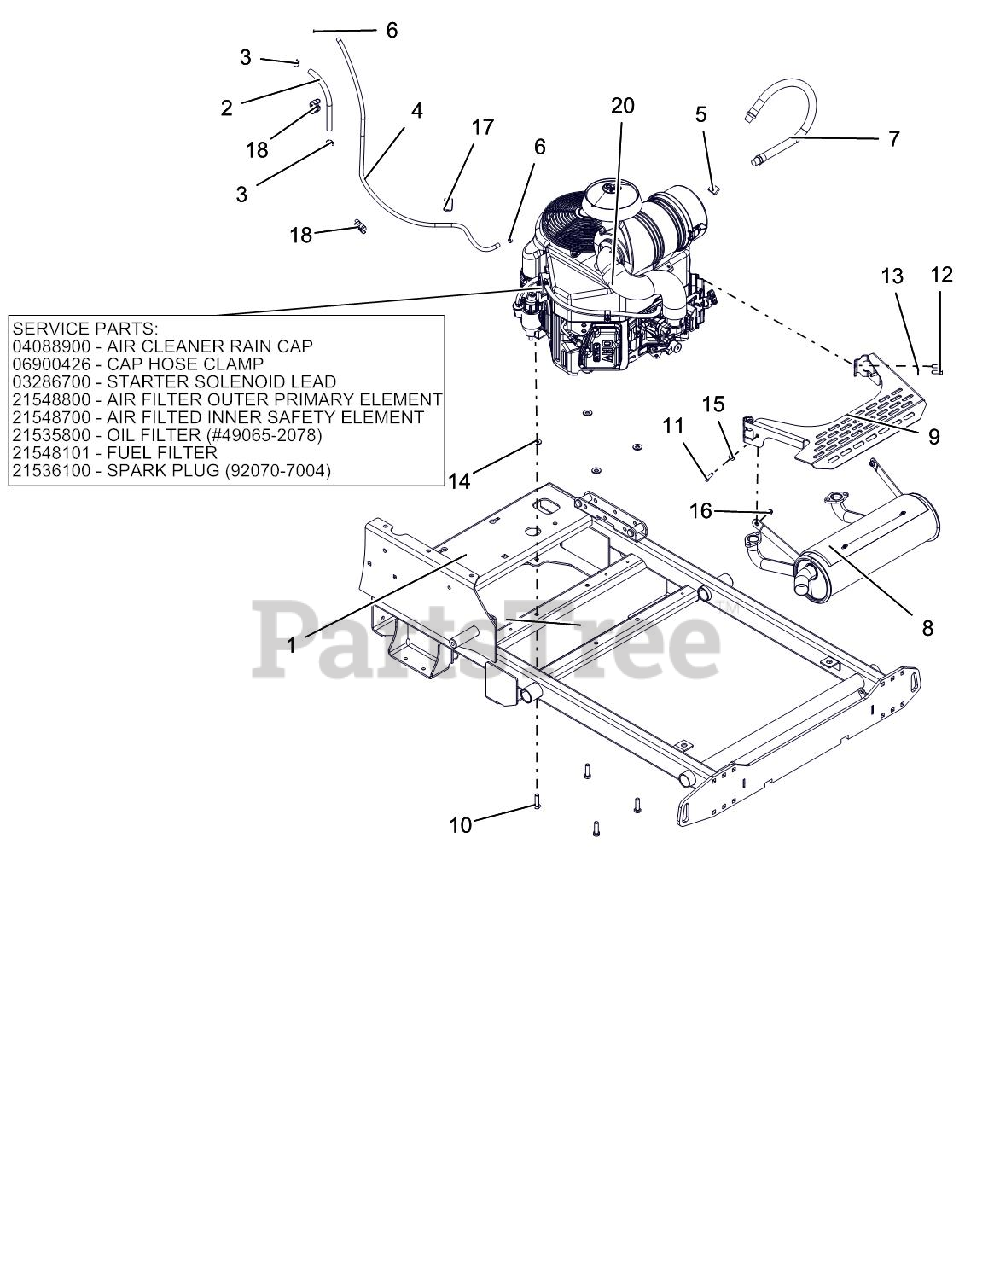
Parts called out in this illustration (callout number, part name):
1	WMT,FRAME,48-52" PRO-STANCE
2	HOSE, .25 LOW-PERM BULK GAS
3	CLAMP, FUEL LINE
4	HOSE, .188 LOW-PERM BULK GAS
5	PIPE CAP 3/8 NPT FEMALE
6	CLAMP-HOSE, SPRING .188
7	DRAIN, M20 OIL
8	EXHAUST, KAWASAKI PROSTANCE
9	SHIELD, MUFFLER
10	BLT-HEX.38-16X1.25 G5YZ NYTORQ
11	BLT-HEX .25-20X1.00 GR5 YWZC
12	BLT-HEX M8-1.25X20 YWZC
13	WSHR-LK .31X.078 REG YWZC
14	WASHER, 3/8" SPRING DISC
15	WSHR-FL-STL.281X.62X.065 YWZC
16	NUT-LK-NYL-FLG .25-20 YWZC
17	CLAMP, COUSHIONED STEEL REV
18	CLIP, T, .38-.50
20	FILTER,OIL - KAW
20	PLUG, SPARK
20	LEAD - STARTER SOLENOID
20	CAP, KAW 11065-7025
20	CLAMP, HOSE #36 SS 1.813-2.75
20	FILTER, OUTER
20	FILTER, INNER - KAW
20	ENGINE, KAWASAKI FX730
20	FUEL FILTER-KAWASAKI FR
